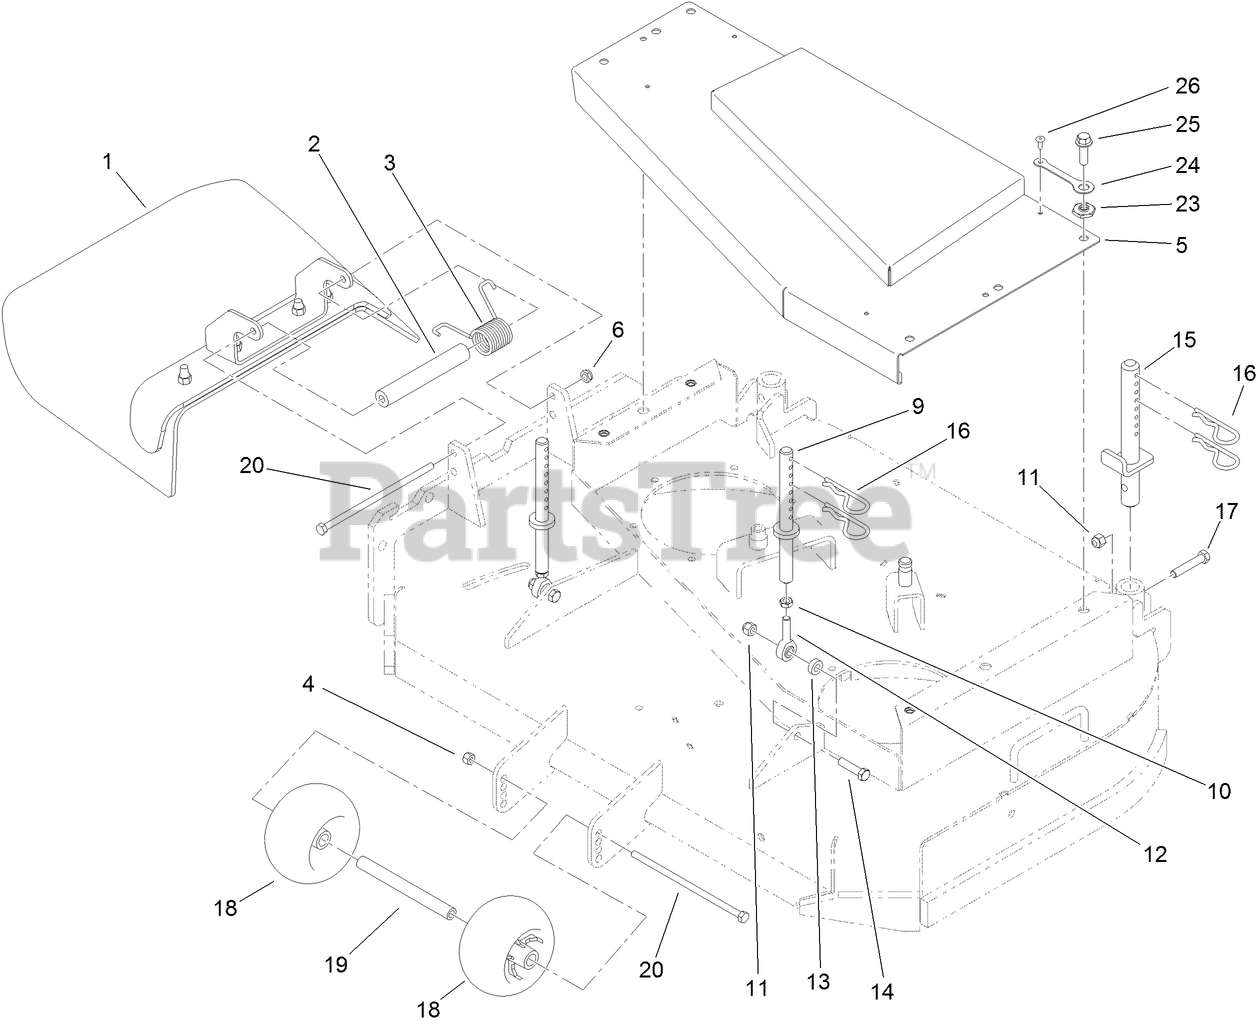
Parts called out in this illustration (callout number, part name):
1	DEFLECTOR ASM
2	SPACER
3	SPRING-TORSION
4	NUT-LOCK, NI
5	COVER-BELT, DECK
6	NUT-LOCK, NI
9	FRONT PIN ASM
10	NUT-HJ
11	NUT-LOCK, NI
12	BALLJOINT
13	SPACER
14	SCREW-HH
15	REAR PIN ASM
16	PIN-HAIR
17	SCREW-HH
18	ROLLER-SCALP, ANTI
19	SPACER-WHEEL
20	SCREW-HH
23	NUT-SHOULDER
24	LANYARD-3 INCH
25	SCREW-HHF
26	RIVET-BLIND
